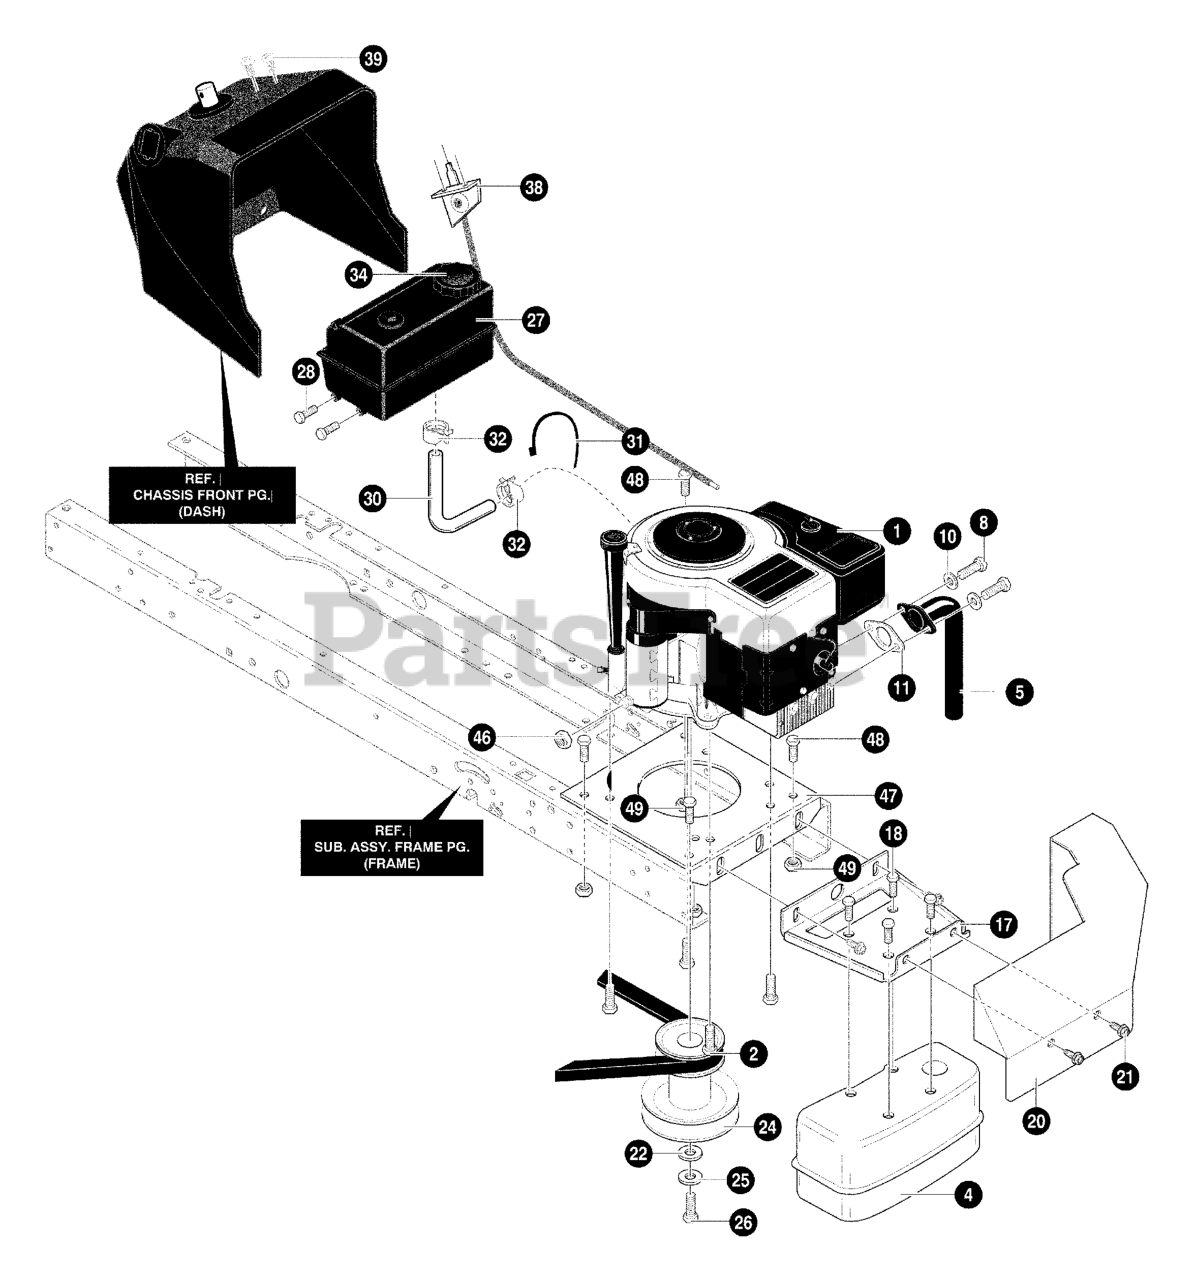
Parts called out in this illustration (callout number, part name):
1	Engine *
2	SCREW, 3/8-16 x 1.25
4	MUFFLER
5	EXHAUST PIPE
8	SCREW, 5/16-18 x 0.75
10	WASHER
11	GASKET, Exhaust
17	BRACKET MUFFLER
18	SCREW, 1/4-20X .75
20	HEAT SHIELD
21	SCREW, 5/16-18 x 0.75
24	PULLEY, STACK
26	SCREW, 7/16-20
27	TANK, FUEL
30	Fuel Line (Must cut to length)
31	TIE, CABLE
32	CLAMP, HOSE
34	CAP, FUEL
38	THROTTLE CONTROL
39	SCREW, 10-24X.63
46	NUT, 1/4-20
47	PLATE, ENGINE
48	SCREW, 5/16-18 x 0.75
49	NUT, 5/16-18 (15X88)
